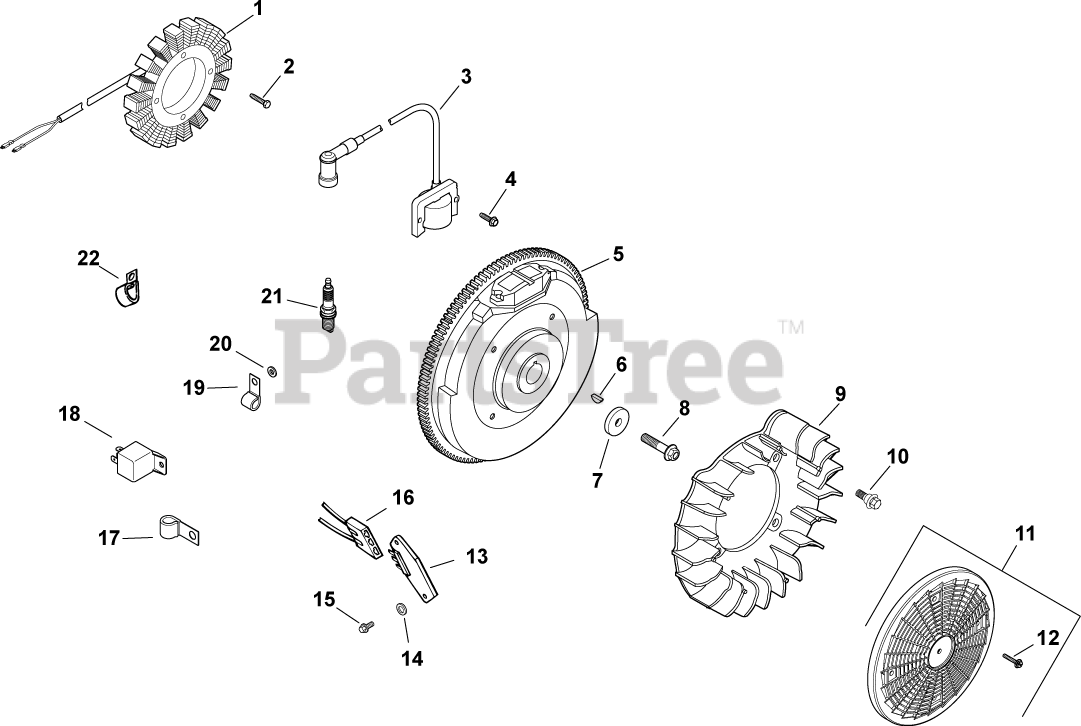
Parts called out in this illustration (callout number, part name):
1	KIT, 25 AMP STATOR ASSY.
2	SCREW, THD FROM M5X0.8X30
3	KIT, MODULE IGNTN (CDI FIXED)
4	SCREW, FLG THD FRM M5X.8X20-(#25086399S)
5	FLYWHEEL, PAINTED-USE 24 025 59-S
6	KEY, 3/16" X 5/8"
7	WASHER, FLAT 13/32"
8	SCREW, FLG M10X1.5X45 - (#25086361S)
9	FAN USE 24 755 253-S
10	BOLT, SHOULDER
11	KIT, GRASS SCREEN
12	SCREW, FLG SEMS M4X.7X25
13	REG/RECTIFIER (20/25 AMP)-USE 25 403 20-
14	WASHER, FLAT 7/32"
15	SCREW, PHL HD #11-16X7/8"
16	CONNECTOR, BODY (KM)-USE 25 155 41-S
17	CLIP, CABLE
19	CLIP, CABLE
20	WASHER, FLAT 1/4" (O.D. 1/2")
21	PLUG, SPARK (PRO SERIES)
22	CLIP, TUBE & WIRING (KM)
